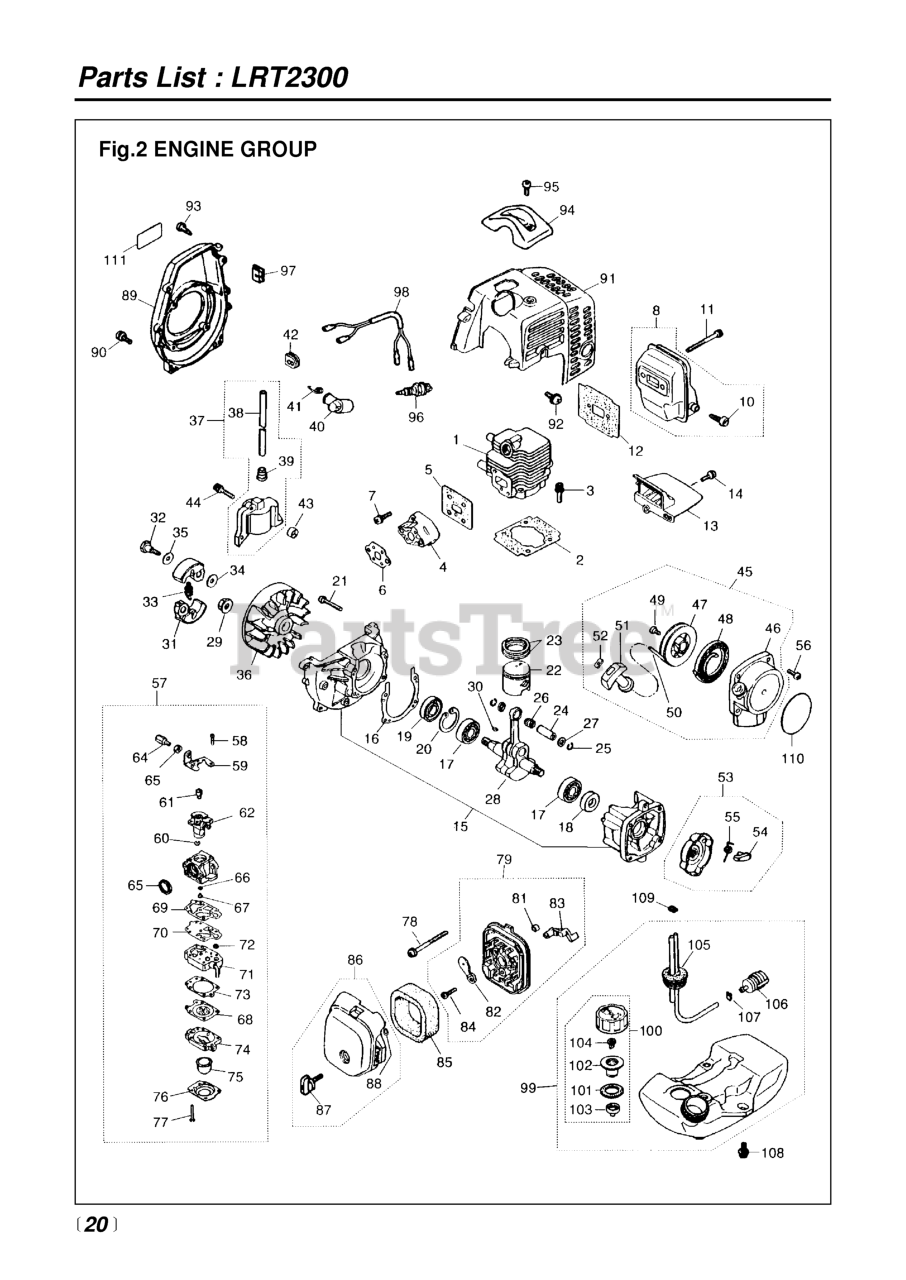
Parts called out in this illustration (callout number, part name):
1	CYLINDER
3	BOLT, M5 X 22
5	GASKET (RPLS -13120)
6	GASKET (REPLACES -13130)
7	SCREW, M5X20 (RPLS.1400-75510)
8	MUFFLER ASSY (RPLS 5501- )
10	ARRESTER (RPLS 5850-15140)
11	BOLT, M5 x 50
12	GASKET, MUFFLER (RPLS -15111)
14	SCREW, M4 X 16
15	CRANKCASE
16	GASKET (RPLS -21140)
17	BEARING
18	SEAL, OIL (RPLS 1100-21210)
19	SEAL, OIL (RPLS 1140-21220)
20	RING, SNAP, M28 x 1.2
21	BOLT, M5 X 30
22	PISTON (REPLACES 1140-41110)
23	RING, PISTON (RPLS 1850-41210)
24	PIN, PISTON 5x8x26
25	RING, SNAP (RPLS 1101-41320)
27	WASHER
28	CRANKSHAFT (RPLS 1850-42000)
30	KEY
31	SHOE (RPLS 1100-51114)
32	BOLT
33	SPRING, CLUTCH (RPLS-51220)
34	WASHER, FLAT (USE 182303)
36	ROTOR
37	COIL ASSY (RPLS 5500-71200)
38	CORD
39	CAP
41	SPRING
42	GROMMET
43	SPACER (RPLS -71260)
44	BOLT
45	RECOIL ASSEMBLY
46	CASE
47	REEL
48	SPRING, SPIRAL
49	SCREW (RPLS -75150)
51	KNOB
52	PLATE, STOPPER
53	PULLEY ASSY (RPLS -75210)
54	RATCHET (RPLS 1850-75220)
55	SPRING, RETURN
56	SCREW, M4 X 16
57	CARBURETOR
58	SCREW
60	RING
61	SWIVEL
62	VALVE ASSY
63	SCREW, CABLE ADJUSTER
64	NUT, CABLE ADJUSTER
65	RING, PACKING
66	RING, O
67	JET
68	DIAPHRAGM (USE 4810-81260)
69	GASKET, PUMP
70	DIAPHRAGM
71	BODY, PUMP
73	GASKET, DIAPHRAGM
74	BODY, PURGE
75	PUMP, PRIMING
76	COVER, PUMP
77	SCREW
78	SCREW, M5 x 60
79	BODY-A (RPLS -82101)
81	SLEEVE
82	PLATE, CHOKE (RPLS-82130)
83	LEVER, CHOKE
84	SCREW (REPLACES 50030272)
85	ELEMENT
87	KNOB (RPLS -82220)
88	RING
89	COVER, FAN (RPLS-31110)
90	SCREW, M5X20 (RPLS.1400-75510)
91	COVER, ENGINE (RPLS -32111)
92	SCREW, M5 x 12
93	SCREW, HOUSING
94	GUARD, PLUG
95	SCREW,M5 X 14 (RPLS 1400-15510
98	CORD COMP (RPLS -73200)
101	PACKING
103	HOLDER, CAP
104	VALVE (NLA WHEN OUT)
105	PIPE COMPLETE
106	FILTER (RPLS 1850-85300)
107	CLIP (REPLACES 2841-31280)
108	SCREW
109	CLIP
110	LABEL, RECOIL
